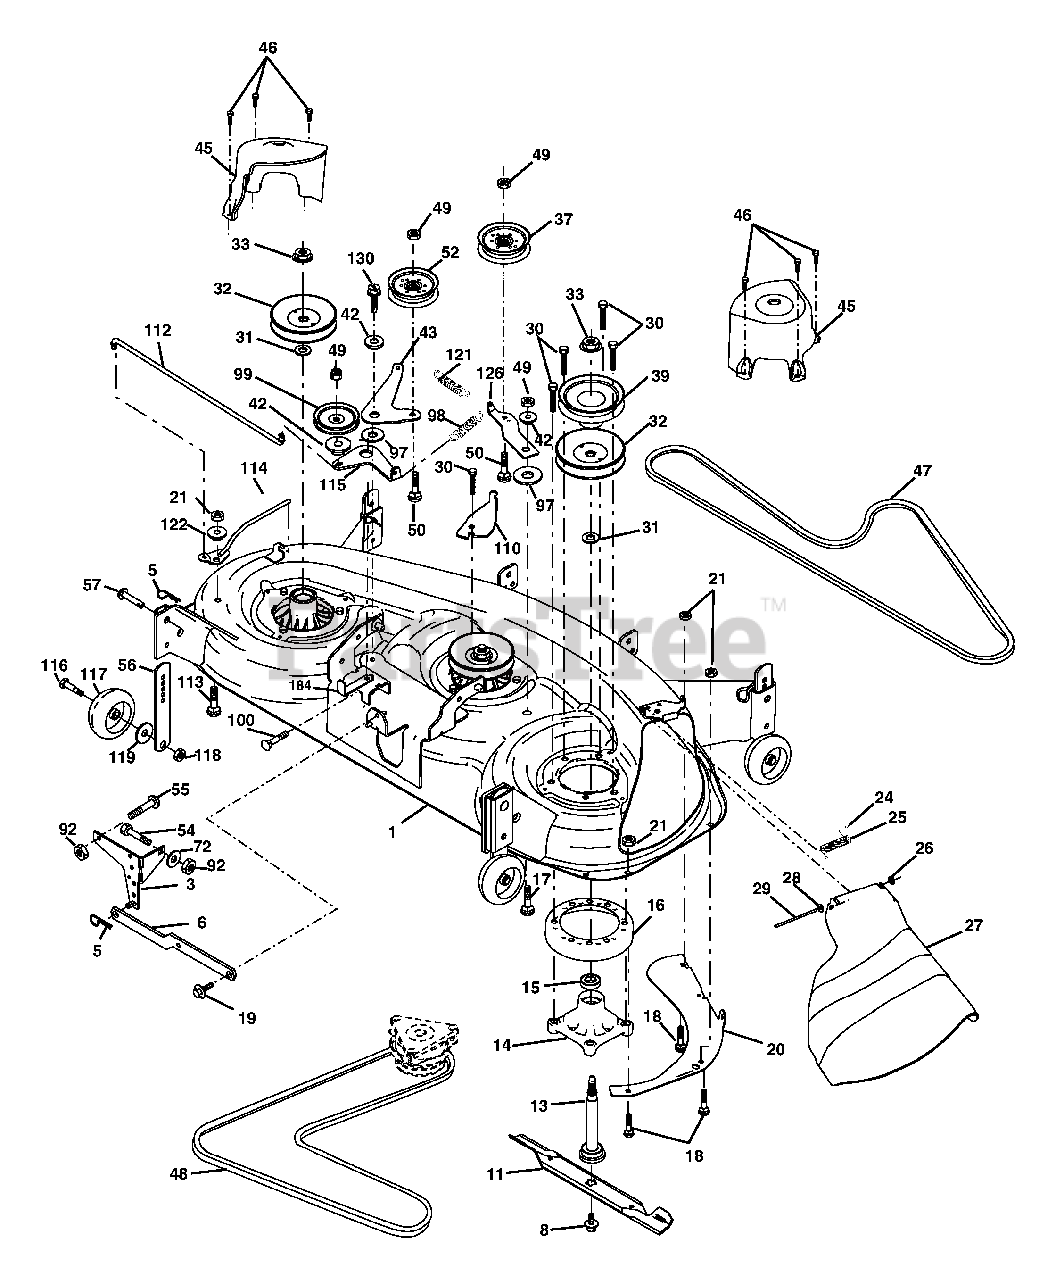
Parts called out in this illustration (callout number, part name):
1	Deck Weldment Mower 48
3	Bracket Asm., Sway Bar
5	Retainer Spring
6	Arm, Suspension, Rear Sway Bar Deck
8	Bolt 7/16 Asm. Blade
11	Blade, 48" Hi-Lift
11	Blade, 48" Mulching
13	Shaft Asm. w/Lower Bearing
14	Mandrel Asm. Housing
15	Bearing, Ball, Mandrel
16	Stripper Mandrel Deck
17	Bolt RDHD Sq Neck 3/8-16 x 1.25
18	Bolt, Carriage 5/16-18 x 5/8
19	Bolt, Hex Hd, Shoulder 5/16-18
20	Baffle, Vortex Mower
21	Nut, Crownlock 5/16-18 unc
24	Cap, Sleeve
25	Spring, Torsion
26	Nut, Push
27	Deflector Shield
28	Washer 11/32 x 5/8 x 16 Ga.
29	Rod, Hinge
30	Screw, Thdroll Washer Head
31	Washer, Spacer
32	Pulley, Mandrel
33	Nut, Flg. Top Lock Cntr.9/16
37	Pulley, Idler, Flat
39	Pulley, Idler, Driven
42	Spacer, Retainer
43	Arm, Idler Secondary
45	Cover, Mandrel Deck
46	Screw, Thdroll. 1/4-20 x 5/8
47	V-Belt, Mower, Secondary
48	V-Belt, Mower, Primary
49	Nut, Lock 3/8-16 unc
50	Bolt, Carr. 3/8-16 x 1-1/2 Gr. 5
52	Pulley Idler Flat
54	Bolt Fin Hex 3/8-16 x 1
55	Bolt Carriage Sqnk. 3/8-16 x 1
56	Bar Pnt Adj.
57	Pin Head Rivet
72	Washer 13/32 x 13/16 x 12 Ga.
92	Nut Lock Hex 3/8-16
97	Washer Hardened
98	Spring Primary Drive
99	Pulley Idler"V"
100	Bolt RDHD Sqnk 3/8-16 unc x 2
110	Arm Spring Break
112	Link Tension Relief Lever
113	Bolt 5/16-18 x 3/4
114	Tension Asm. Relief Lever
115	Arm Spring Tension Relief
116	Bolt, Shoulder
117	Gauge Wheel
118	Nut, Centerlock 3/8-16 unc
119	Washer 3/8 x 7/8 x 14 Ga.
121	Spring Secondary Drive
122	Bushing Pivot Tension Relief
126	Arm, Idler, Primary Deck
130	Screw 3/8-16 x 1.0
184	Keeper Belt Idler
184	Mandrel Asm. Service
184	Relplacement Mower, Complete
